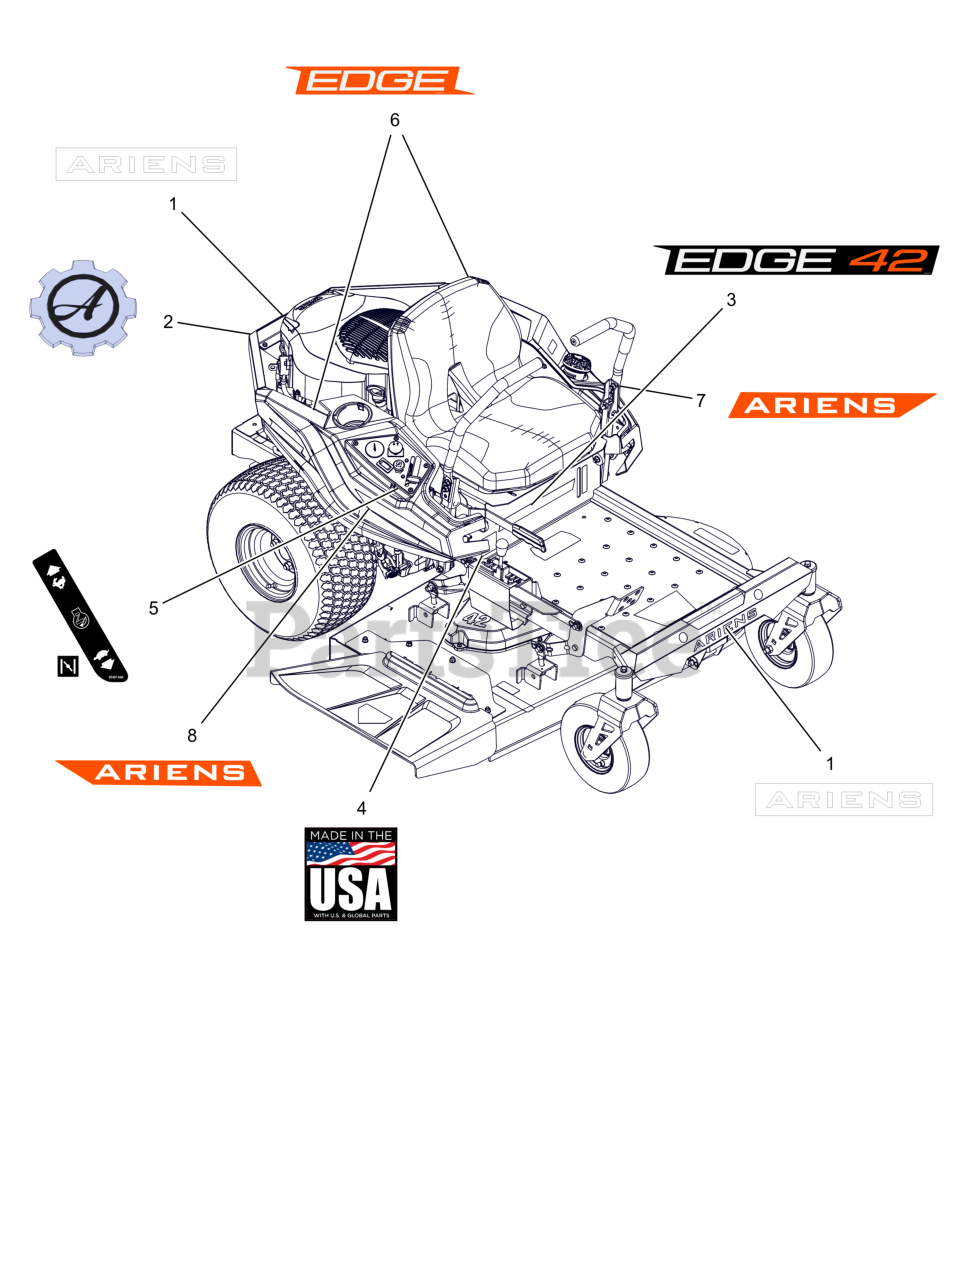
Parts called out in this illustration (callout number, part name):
1	DECAL - ARIENS 9.625"
2	DECAL, ARIENS-GEAR BADGE -THK
3	DECAL, EDGE 42 - KICKPLATE
4	DECAL, MADE IN USA
5	DECAL, SPEED CONTROL
6	DECAL, EDGE FENDER
7	DECAL, ARIENS FENDER LH
8	DECAL, ARIENS FENDER RH
